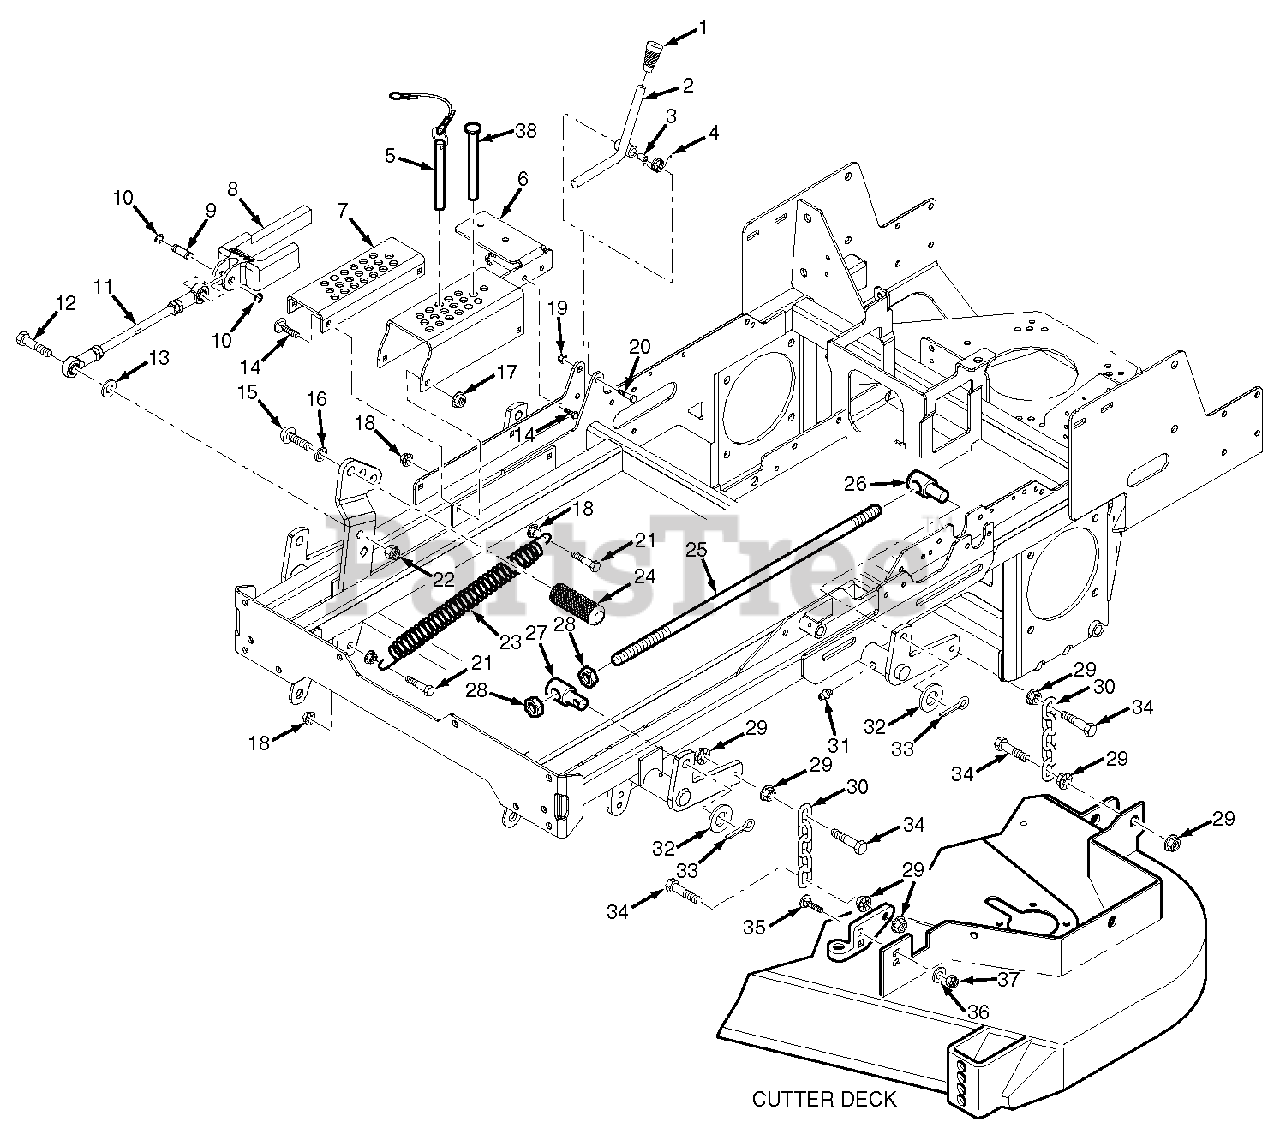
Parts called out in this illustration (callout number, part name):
1	Grip, Deck Latch
2	Deck Latch Assembly w/Grip
3	Spacer, Deck Latch
4	Spring, Torsion Return Lever
5	Ring Pin Assembly w/Lanyard
6	Adjustment Bracket, Upper Cut Height
7	Adjustment Bracket, Lower Cut Height
8	Slide, Height Adjustment
9	Pin, Deck Lift
10	Retaining Ring, 1/2" External "E"
11	Linkage, Deck Lift
11	Rod End, 1/2-20 RH Female
11	Rod End, 1/2-20 LH Female
11	Nut, 1/2-20 UNF Jam
11	Nut, 1/2-20 UNF LH Jam
12	Bolt, Hex Head 1/2-13 x 2"
13	Flatwasher, 1/2-.531 X 1.062 X .095
14	Bolt, Hex Head 5/16-18 x 1"
14	Lockwasher, 5/16" Spring
15	Capscrew, 5/8-11 x 1-1/2"
16	Lockwasher, 5/8" Spring
17	Nut, Serrated Flange 5/16-18
18	Nut, Serrated Flange 3/8-16
19	Nut, Elastic Stop 3/8-16
20	Bolt, Hex Head 3/8-16 x 2-3/4"
21	Bolt, Hex Head 3/8-16 x 1-1/2" Grade 8
22	Nut, Elastic Stop 1/2-13
23	Spring, Deck Lift
24	Pedal, Foot Lift
25	Stud, 5/8-11 x 22"
26	Swivel Joint, LH
27	Swivel Joint, RH
28	Nut, 5/8-11 UNC
29	Nut, Serrated Flange 3/8-16
30	Chain
31	Grease Fitting, 1/4-28 Self Tap
32	Flatwasher, 5/8"
33	Cotter Pin, 3/16 x 1"
34	Bolt, Hex Head 3/8-16 x 1-1/2"
35	Bolt, Carriage 7/16-14 x 1-1/4"
36	Flatwasher, 7/16-.500 x 1.25 x .083
37	Nut, Elastic Stop 7/16-14
38	Pin, Locking
